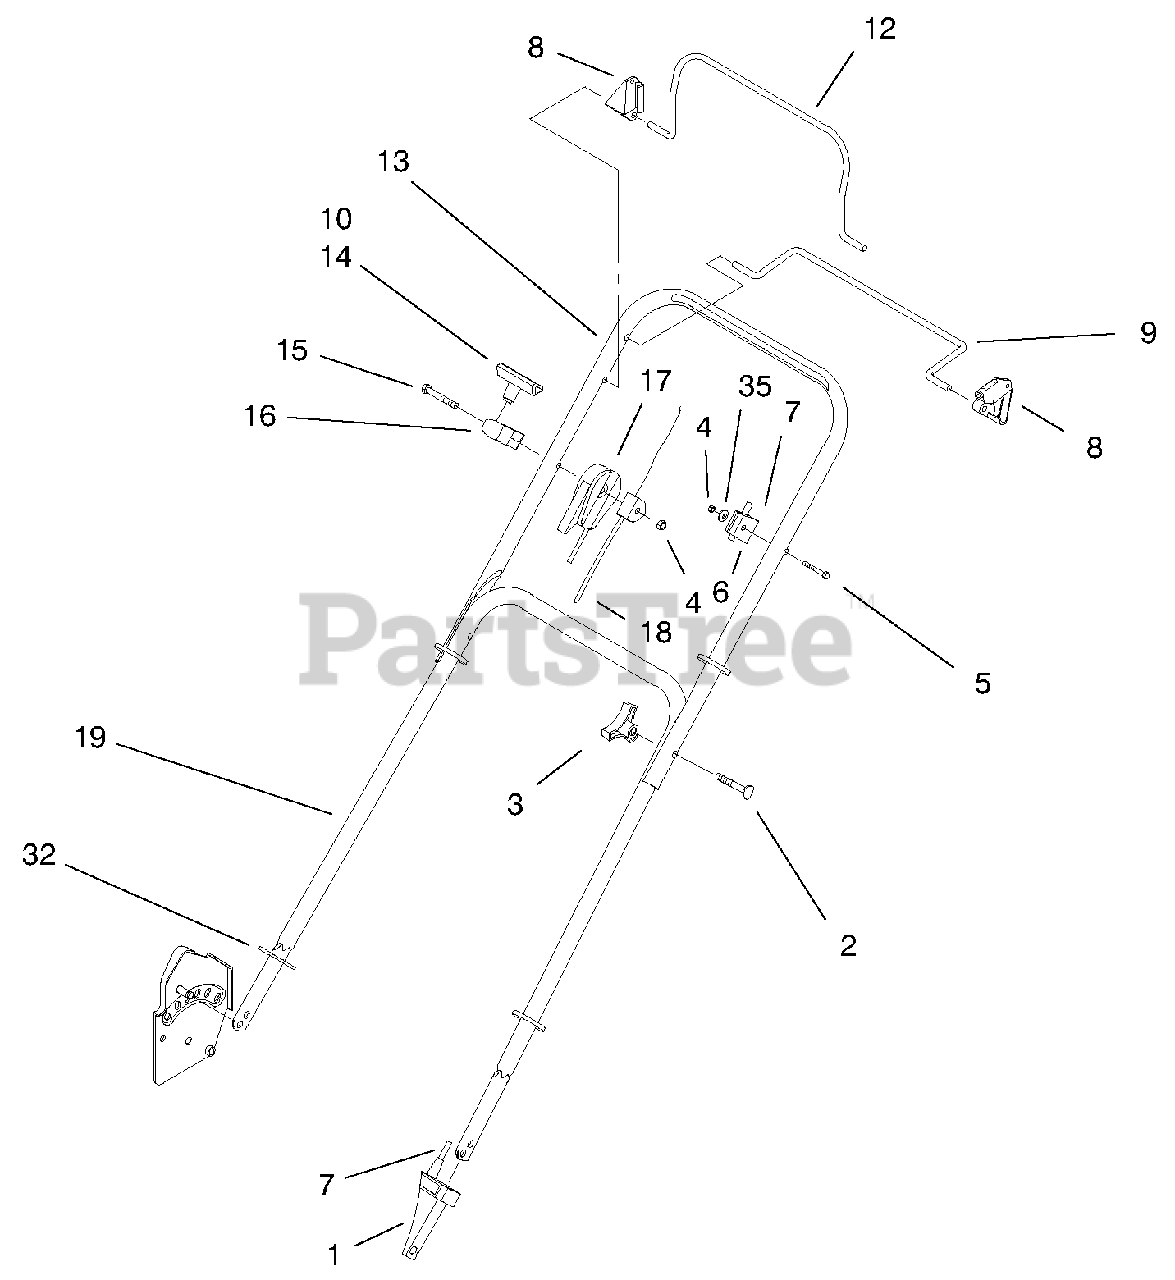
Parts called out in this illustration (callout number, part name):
1	Anchor-Cable
2	Screw-Handle
3	Knob
4	Nut-Lock
5	Screw-Handle
6	Anchor-Cable
7	Cable-Traction
8	Stop-Pivot
9	Bail-Sp Control
10	Staple-Handle
12	Bail-Flywheel Brake
13	Handle Section-Upper
14	Handle-Starter
15	Screw-HH
16	Guide-Rope
17	Cable-Throttle
18	ASM-Brake Cable
19	Handle Section-Lower
32	Handle-Guard
35	Washer-Flat
